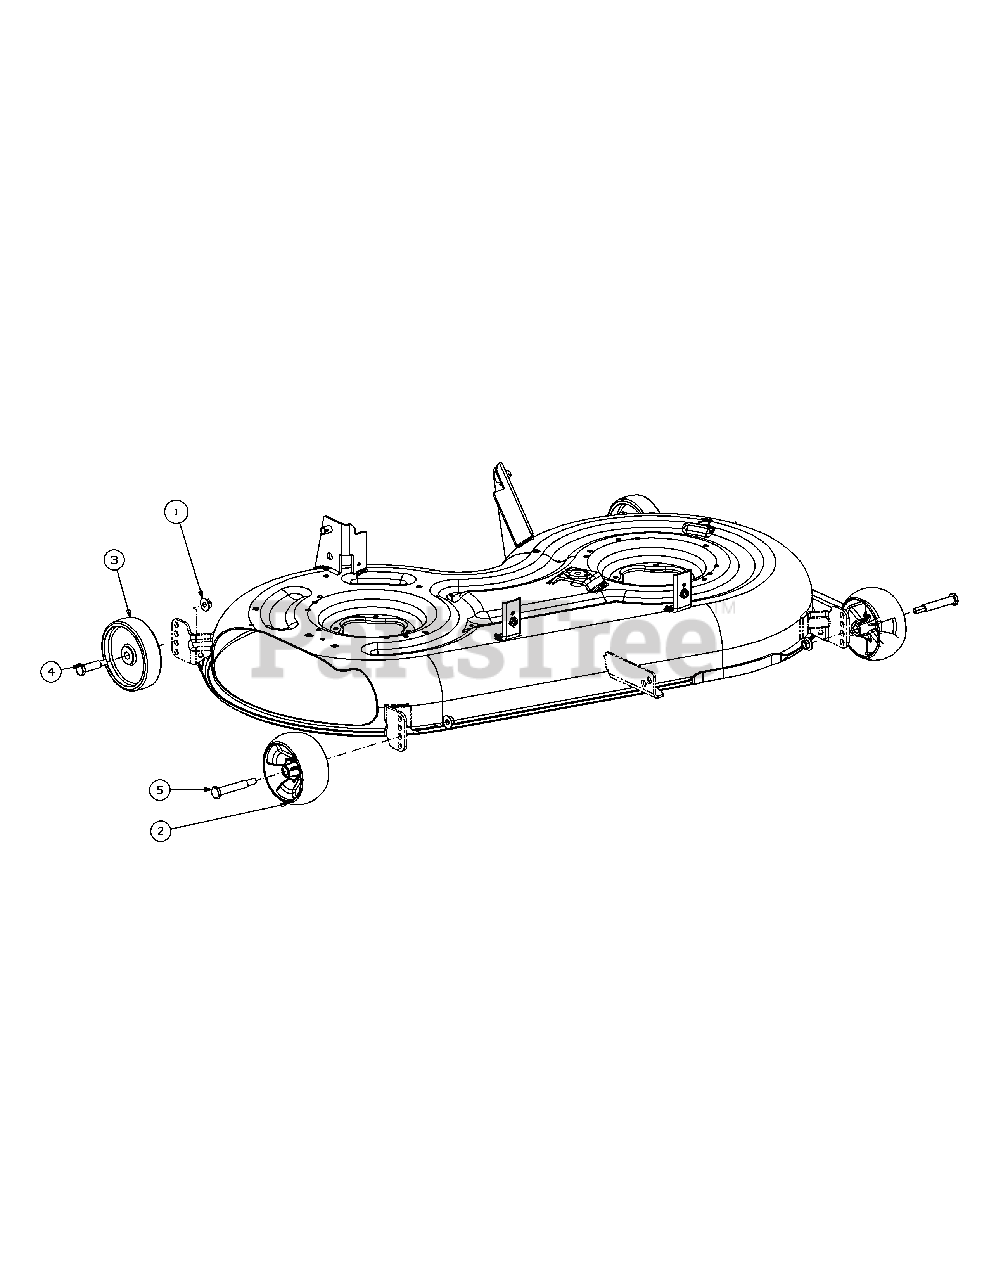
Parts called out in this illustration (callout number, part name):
1	Nut-Flange Lock
2	Wheel:Deck:5.0 Dia B
3	Wheel-Plastic 5X1.
4	Screw-Shld
5	Bolt-Shld .50 X 2.5 X 3/8-16
